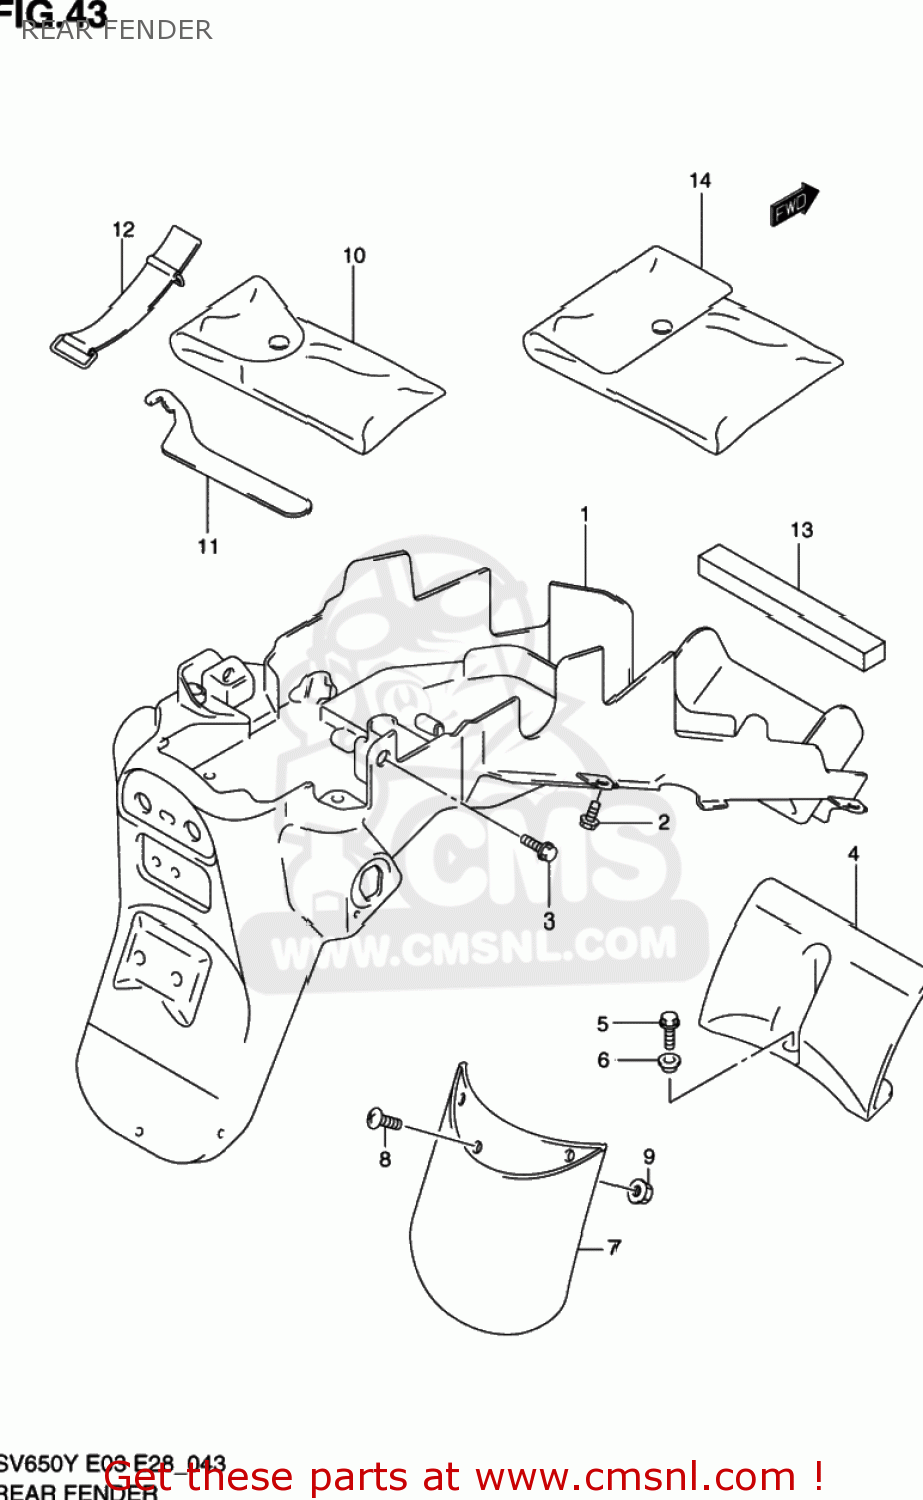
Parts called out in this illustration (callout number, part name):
1	FENDER,RR
2	BOLT(6X16)
3	BOLT(6X16)
4	MUDGUARD,RR FENDER FR LWR
5	BOLT
6	WASHER
7	EXTENSION,RR FENDER
8	SCREW 6X10
9	NUT
10	TOOL ASSY
11	CLAMP
12	BAND,TOOL
13	CUSHION,FRAME COVER
14	BAG COMP,OWNERS MANUAL
